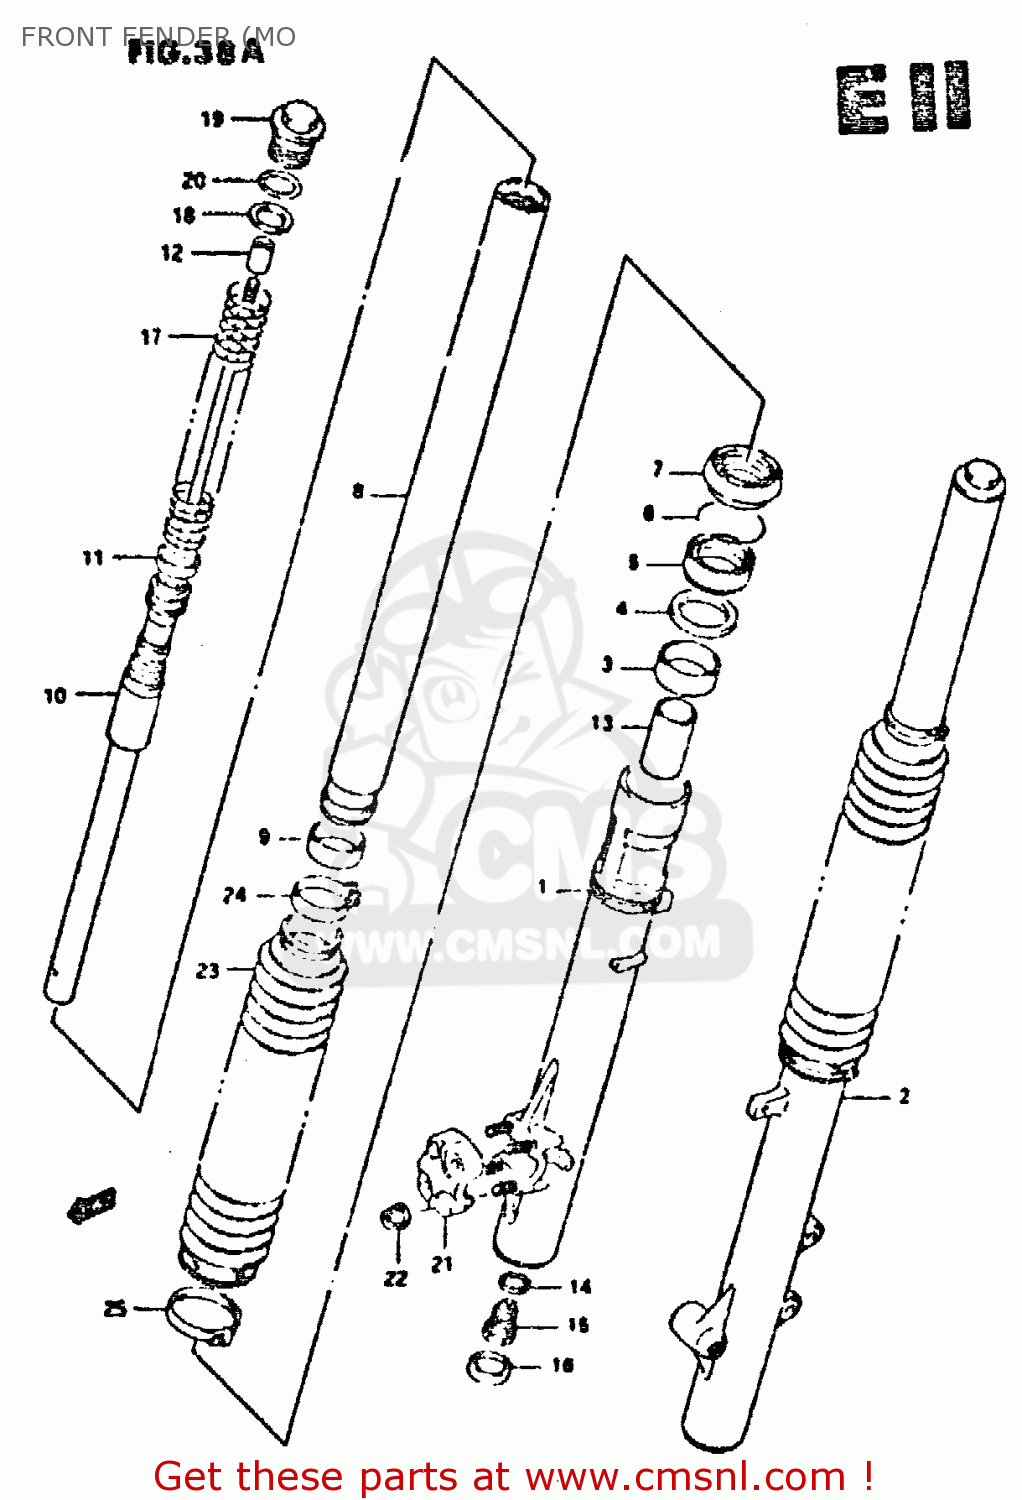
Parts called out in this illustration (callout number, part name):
00000	DAMPER ASSEMBLY,LEFT
1	TUBE,OUTER,RIGHT
2	TUBE,OUTER,L
3	BUSH,GUIDE
4	SPACER,SEAL
5	SEAL,OIL
6	CIRCLIP,FORK OIL SEAL
7	DUST SEAL
8	TUBE,INNER
9	BUSH,SLIDE
10	CYLINDER
11	BUSH,SLIDE
12	NUT,ROD
13	PIECE,OIL LOCK
14	GASKET (NAS)
15	CTR BOLT
16	CAP
17	SPRING,MAIN
18	SEAT,SPRING LWR
19	BOLT,FORK
20	O RING
21	HOLDER,AXLE
22	NUT,HOLDER
23	BOOT
24	BAND,BOOT UPR
25	NUT,HOLDER
26	BOOT
27	BAND,BOOT UPR
28	BAND,BOOT LWR
